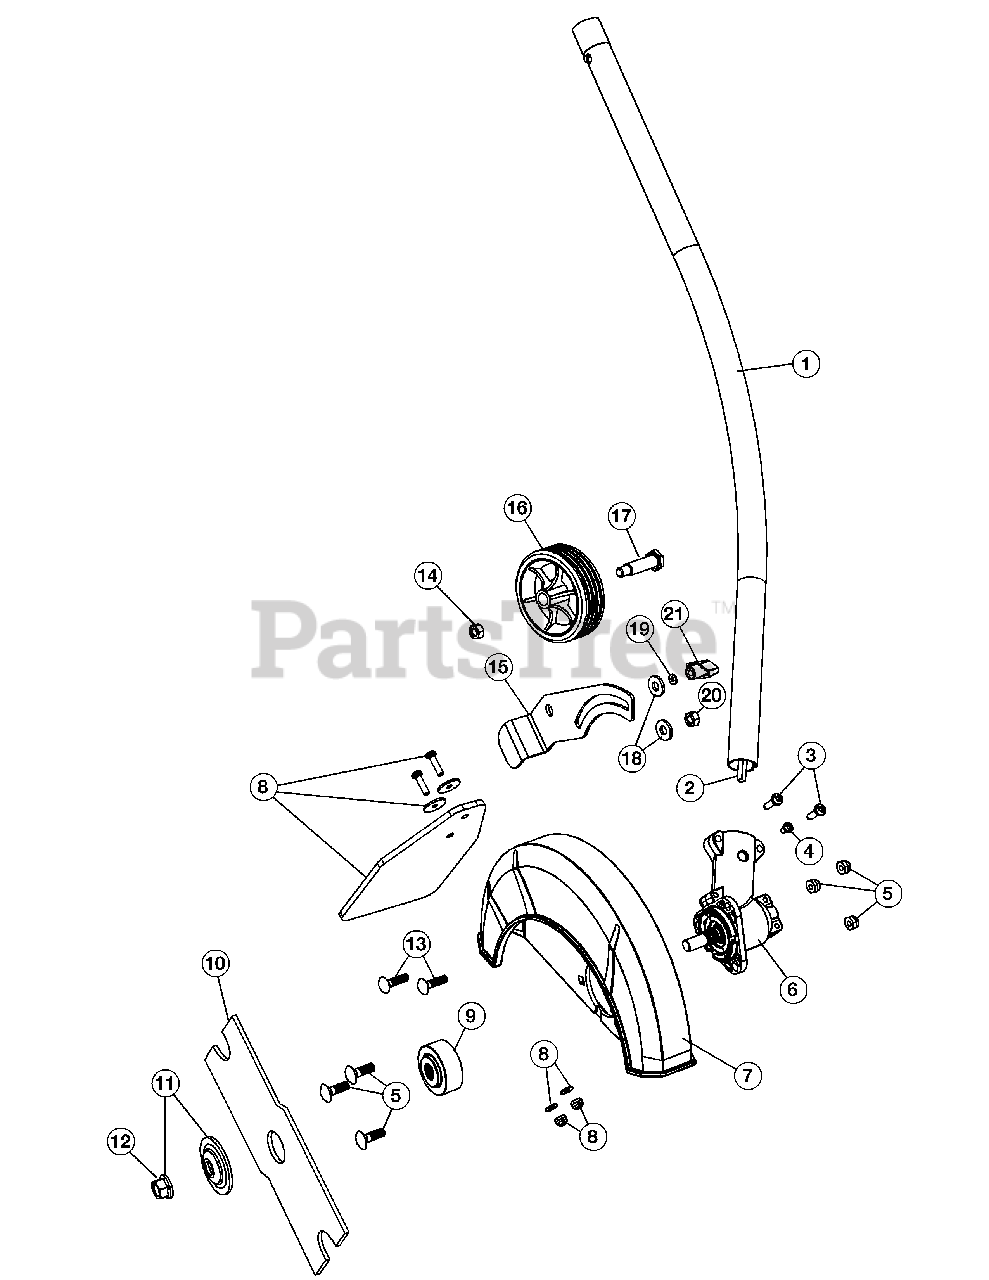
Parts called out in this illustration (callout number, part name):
1	Boom Assembly
2	Drive Shaft
3	Boom Mounting Hardware
4	Anti-Rotation Screw
5	Guard Mounting Hardware
6	Gearbox Assembly
7	Blade Guard
8	Deflector w/Hardware
9	Spacer
10	Blade
11	Blade Clamp Washer
12	Blade Retainer Nut
13	Wheel Bracket Mounting Bolt
14	Nut
15	Edger Guide
17	Shoulder Bolt
19	Washer
21	Edger Guide Knob
